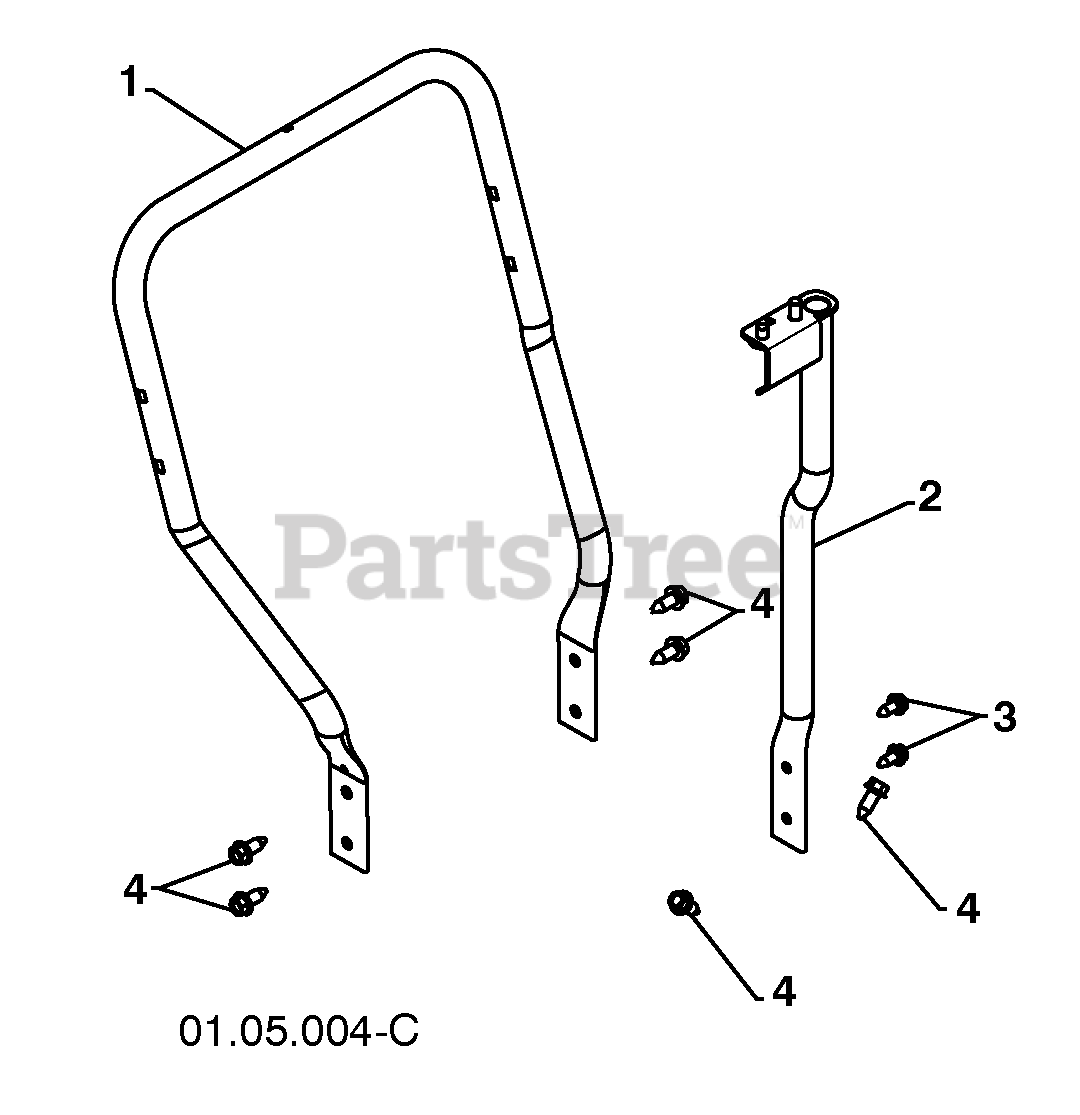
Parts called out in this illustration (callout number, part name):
1	LOWER TUBE
3	BOLT 5/16-18 X .750
4	SCREW 3/8-16 X 1.00
